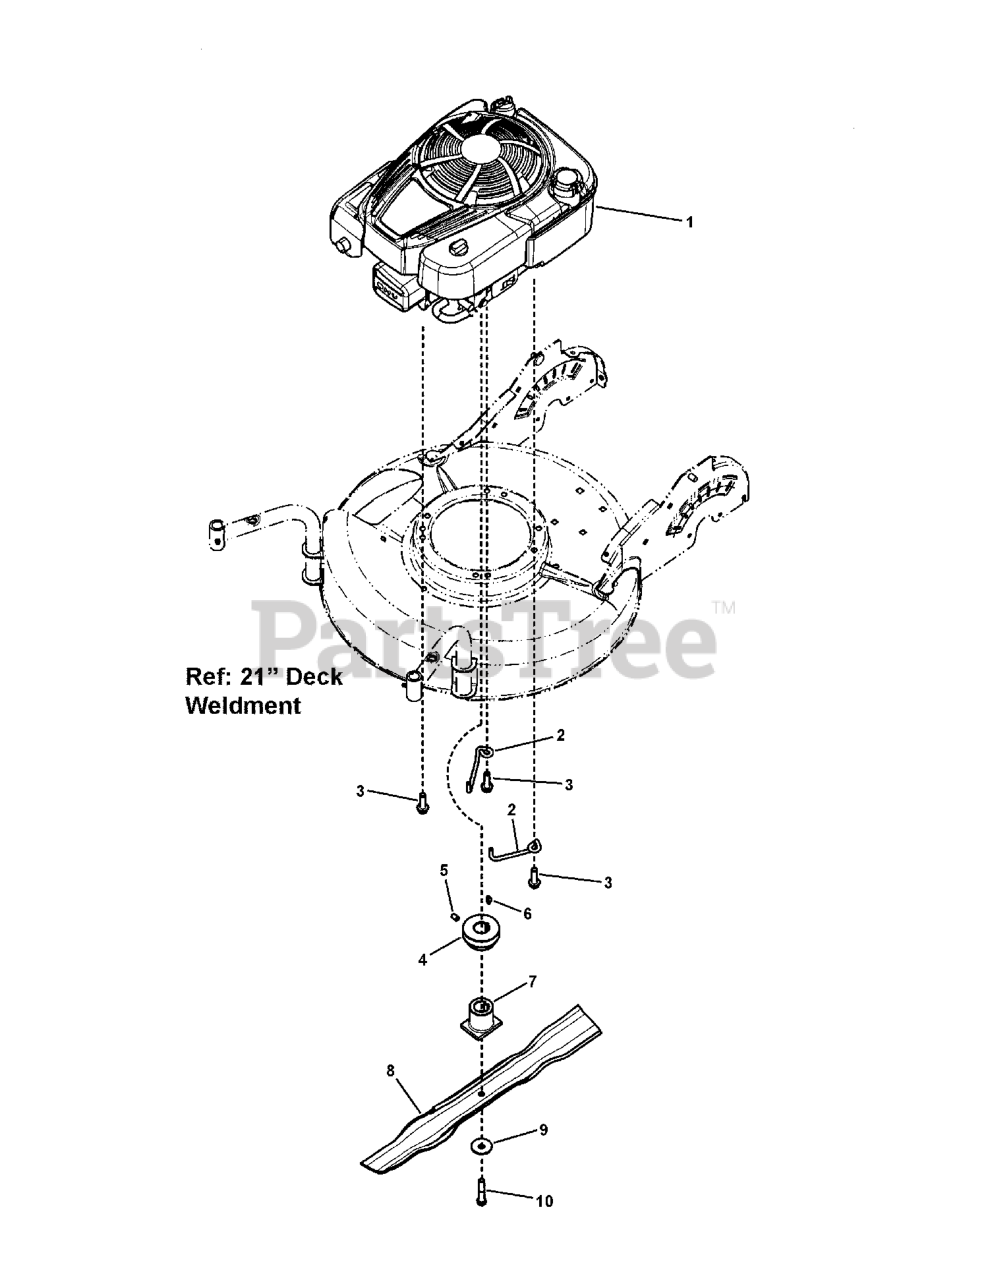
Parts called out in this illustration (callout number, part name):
1	ENGINE, Briggs 875 Gross Professional Torque Series
2	BELT GUIDE
3	SCREW, 3/8-16 x 1-1/4" Hex Washer Self-Tap
4	PULLEY, Engine
5	SET SCREW, 5/16-18 x 1/2" Hex Recess
6	KEY, #HP-506 Hi-Pro
7	BLADE HUB, 21" WBM, Rear Drive, 2 Position
8	BLADE, Wave, 21" Steel Deck
9	WASHER, Cone
10	SCREW, 3/8-24 x 2" Hex Head Cap, GR 5
